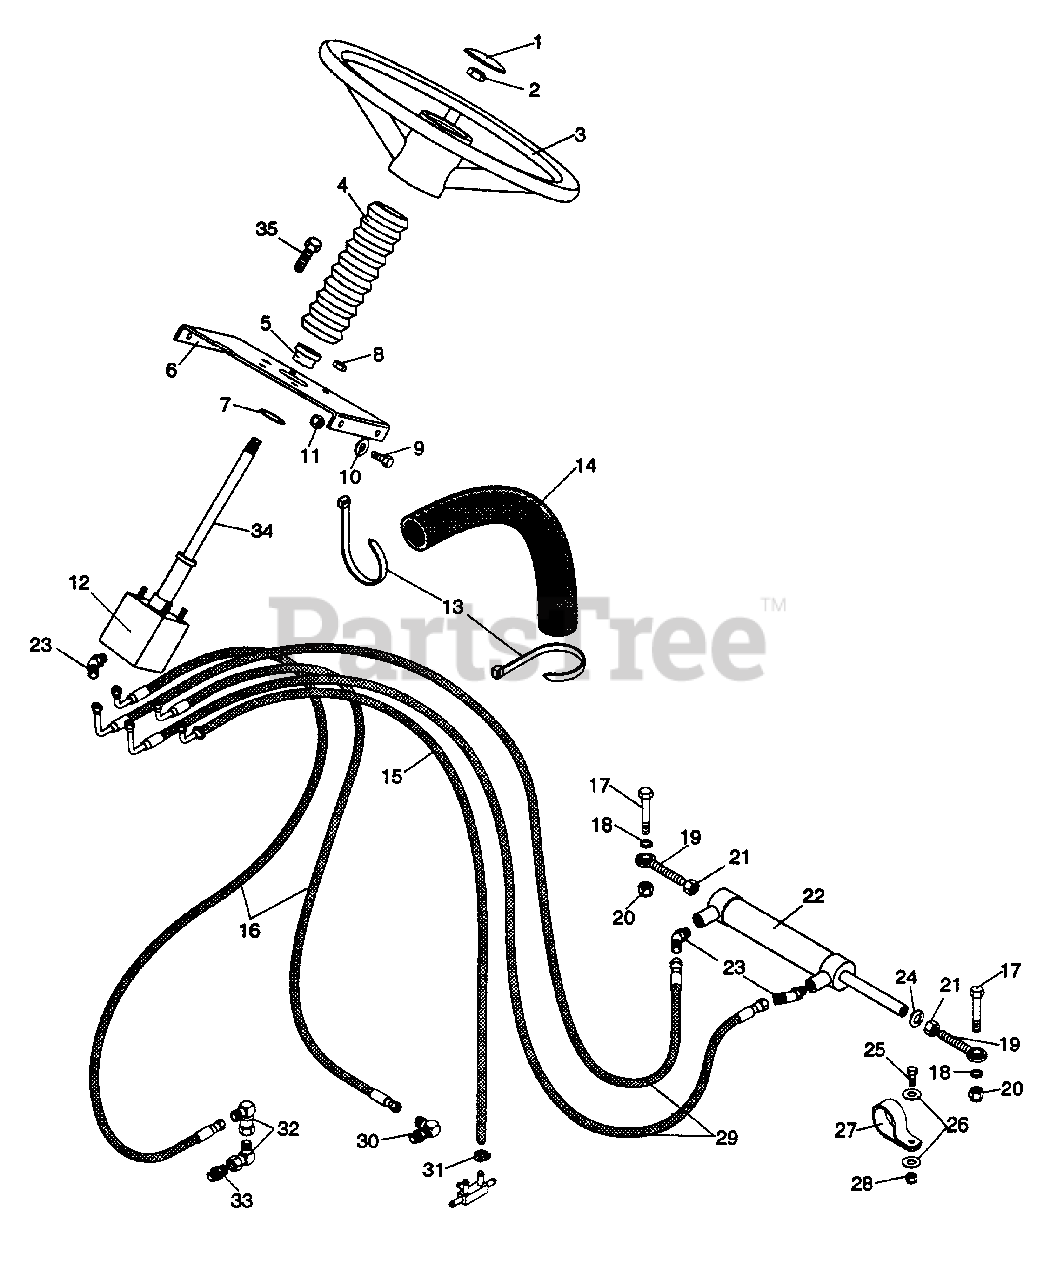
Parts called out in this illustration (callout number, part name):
1	STEERING WHEEL CAP
2	NUT JAM .625 - 11 PL
2	NUT, JAM M16 X 1.5 HEX
3	G-STEERING WHEEL
4	STEERING COLUMN BOOT
5	BSHG-FLG .762 X 1.0 X .580 X 1.48 NY
6	BRKT-STEERING PUMP
7	RG-RING-EXT 1.250 X .060
8	NUT-LK .312-24 W/INSR
9	BLT-HEX .31-18 X .75 PL GR 5
10	WSHR-FL-STL .344 X .688 X .065
11	NUT-LK-NYL .312-18 PL
12	PWR STRG UNIT
12	POWER STEERING UNIT
13	TIE WRAP, BLACK
14	SLEEVE 12
15	ASM, HYDRAULIC HOSE
16	ASM, HYDRAULIC HOSE
17	BLT-HEX .50-13 X 2.00 PL GR 5
18	BUSH., S .520 X .625 X .125 ST
19	ASM, ROD END(R.H.)
20	NUT-LK-NYL .50-13 PL
21	NUT-JAM .50-20 PL
22	CYL, STEERING
23	ADPT, P-H #3503-6-6
24	WSHR-LOCK .50 REG.
25	BLT-HEX .38-16 X 1.00 PL GR 5
26	WSHR-FL-STL .406 X .812 X .065 PL
27	CLAMP, NYLON
28	NUT-LK-NYL .375 - 16 PL
29	ASM, HYDRAULIC HOSE
30	ADPT 2503-6-6
31	HOSE CLAMP
32	GSKT, ADAPTOR
33	ADPT-PIPE .56-18 O RING TO .5
34	COLUMN, STEERING
35	BLT, HEX M6-1 X 20MM
NS	REPAIR KIT, ROSS POWER STEERING
NS	REPAIR KIT, EATON POWER STEERING
NS	DECAL, STEERING WHEEL CAP
